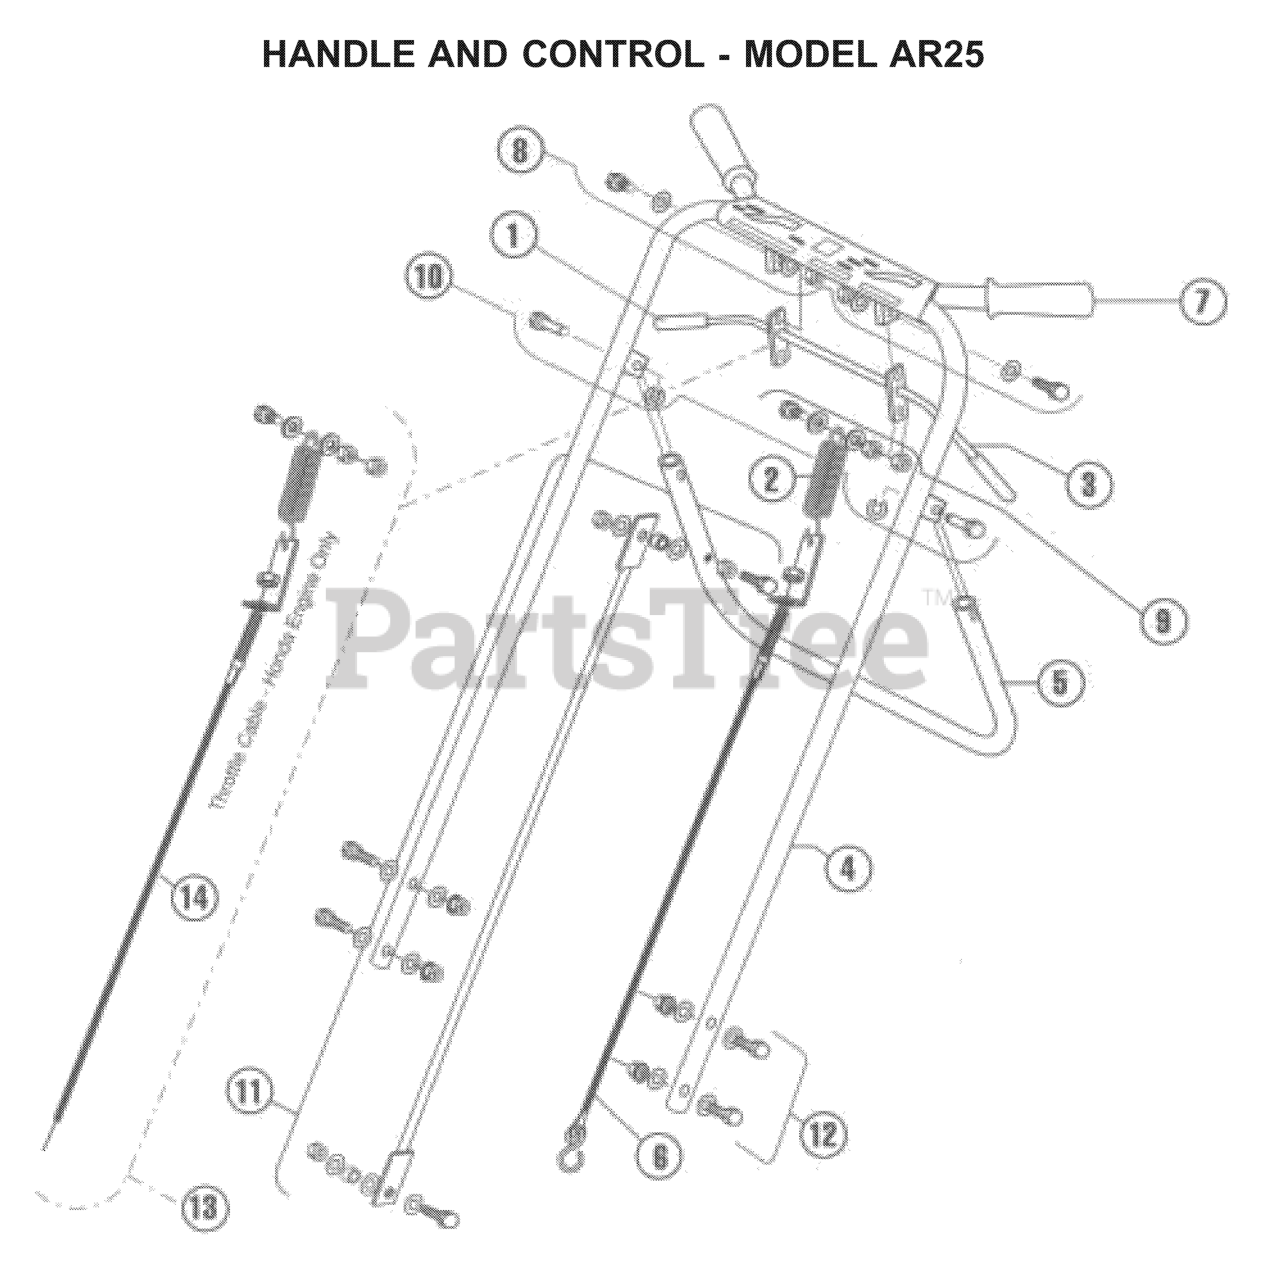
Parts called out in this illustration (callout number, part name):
1	GRIP, CLUTCH
2	SPRING
3	CLUTCH CONTROL KIT HUS
4	HANDLE WITH GRIPS
5	HANDLE, CONTROL, REAR WHEEL
6	CLUTCH CABLE
7	GRIPS, PAIR, 1" ID, BLACK
8	BOLT KIT CLUTCH CONTROL
9	CABLE KIT, CLUTCH
10	PIN KIT, REAR WHEEL
11	CONTROL ROD KIT HV
12	FASTENER KIT, HANDLE
13	THROTTLE CABLE KIT
14	THROTTLE CABLE
540007405	CLUTCH THROTTLE CONTROL HV
